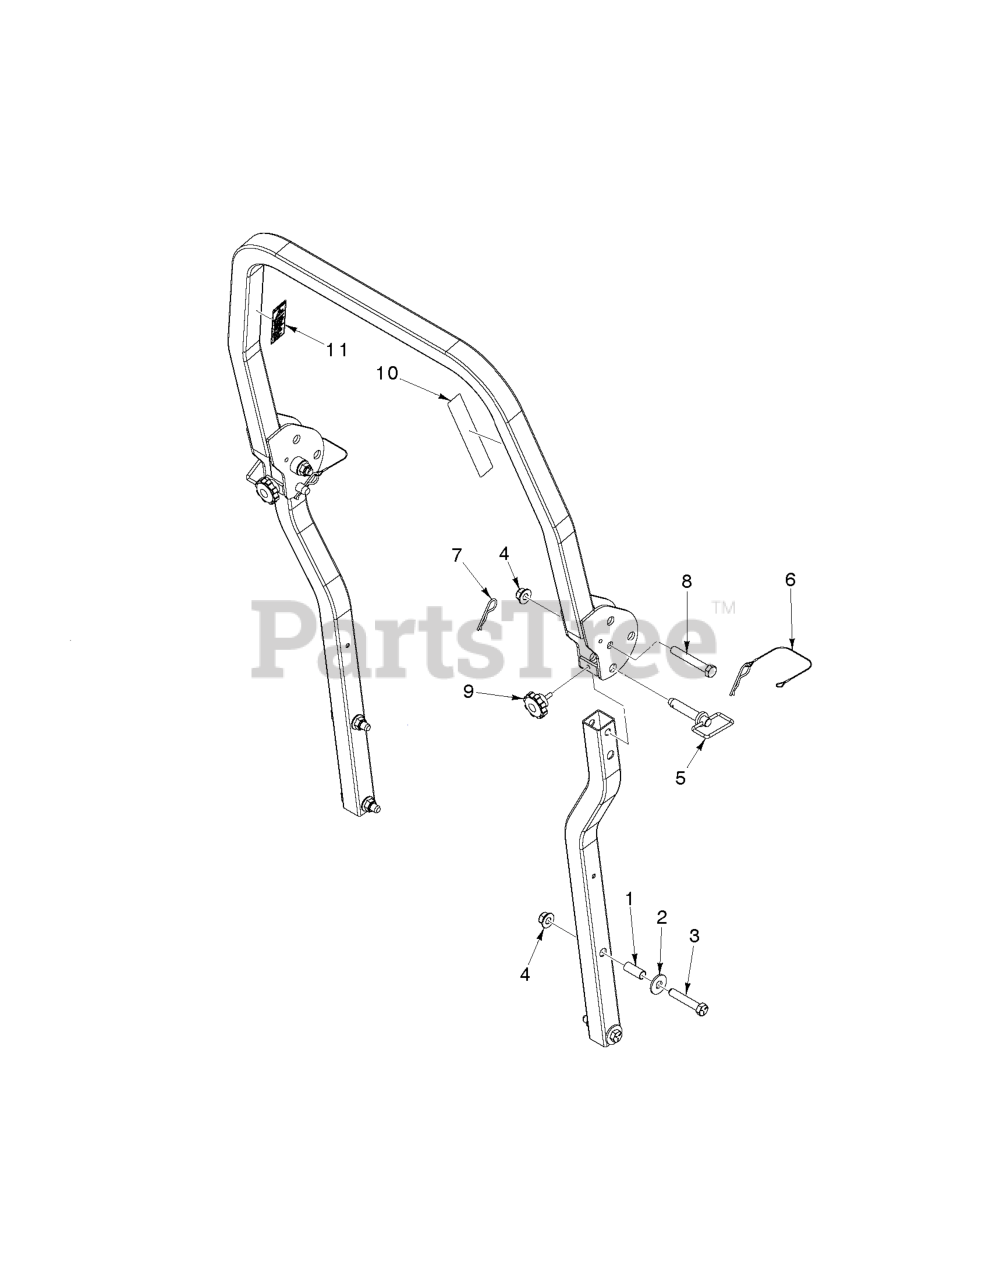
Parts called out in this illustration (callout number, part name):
1	Spacers
2	Washers
3	Bolts
4	Nuts
5	Pins
6	Pins
7	Pins
8	Bolts
9	KNOB.5/16-18X1"BLACK
10	Decals
11	DECAL, ROPS, WARNING
